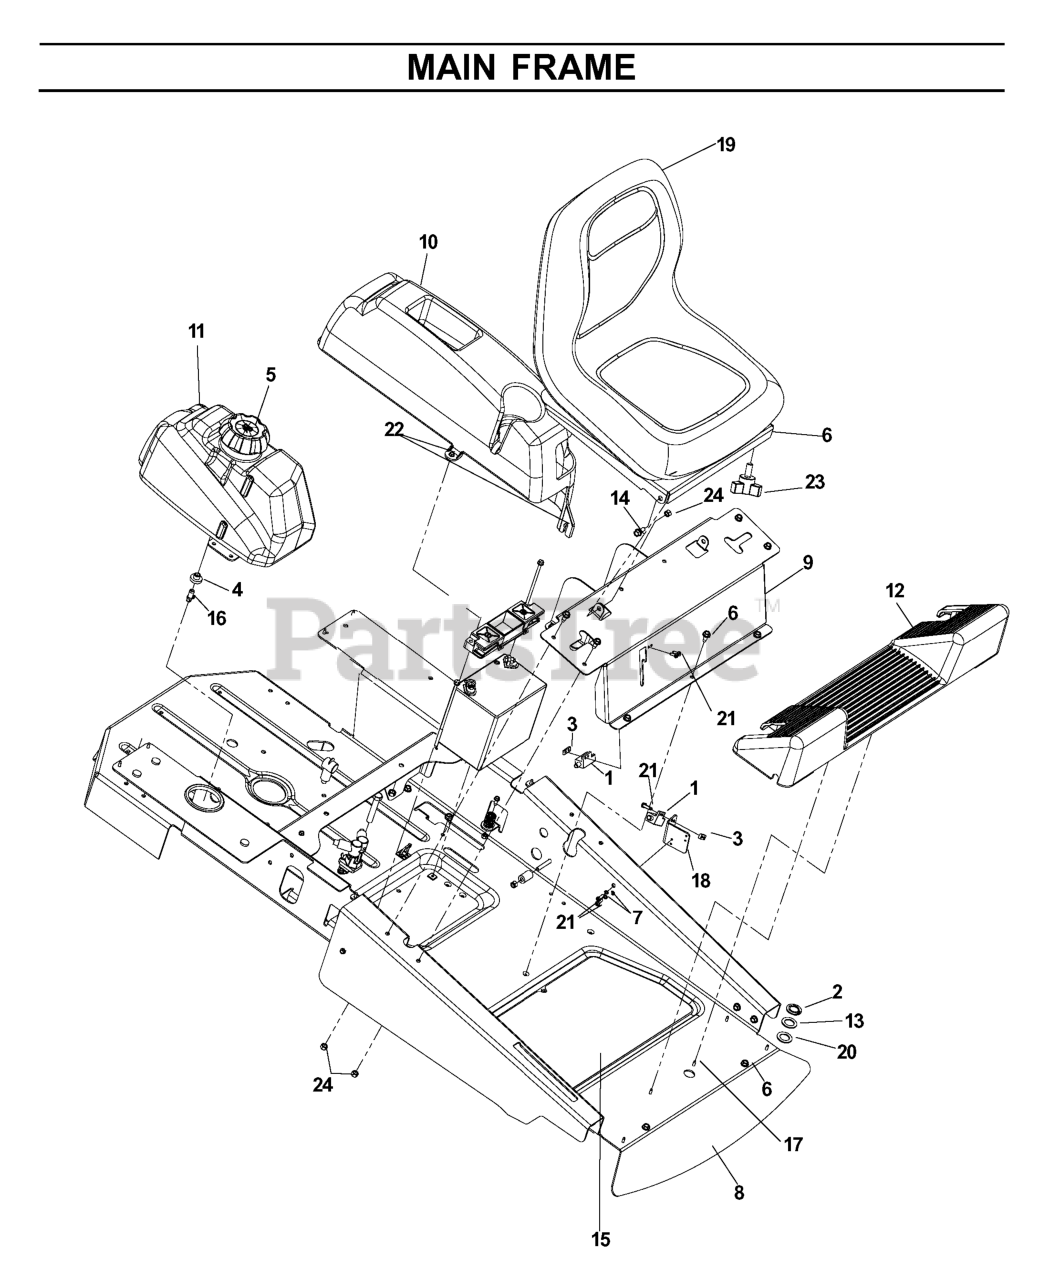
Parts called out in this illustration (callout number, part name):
1	SWITCH, INTERLOCK
2	RETAINING RING, 7/8"
3	TAPPED PLATE
4	RUBBER GROMMET
5	FUEL CAP ANTI-SPLASH
6	SEAT MOUNT, BLACK
7	WASHER - 3/16 LOCK ZD
8	FRAME W/DECALS
9	CONSOLE W/DECALS
10	FENDER LEFT
12	FOOT REST GRAY
14	BOLT, SHOULDER
15	SLIP, MATTING
16	STEM, FUEL TANK
17	SCR #10-12X3/4 HEX WAS HD ZD
19	SEAT.XH150.LOWBACK.GREY.ZTR
20	BSHG .875 X 1.375 X .074 ZD
21	SCREW #10-24 X 5/8
22	SCREW 1/4 X 5/8
23	KNOB W/STUD
24	NUT 5/16 NYLOC
